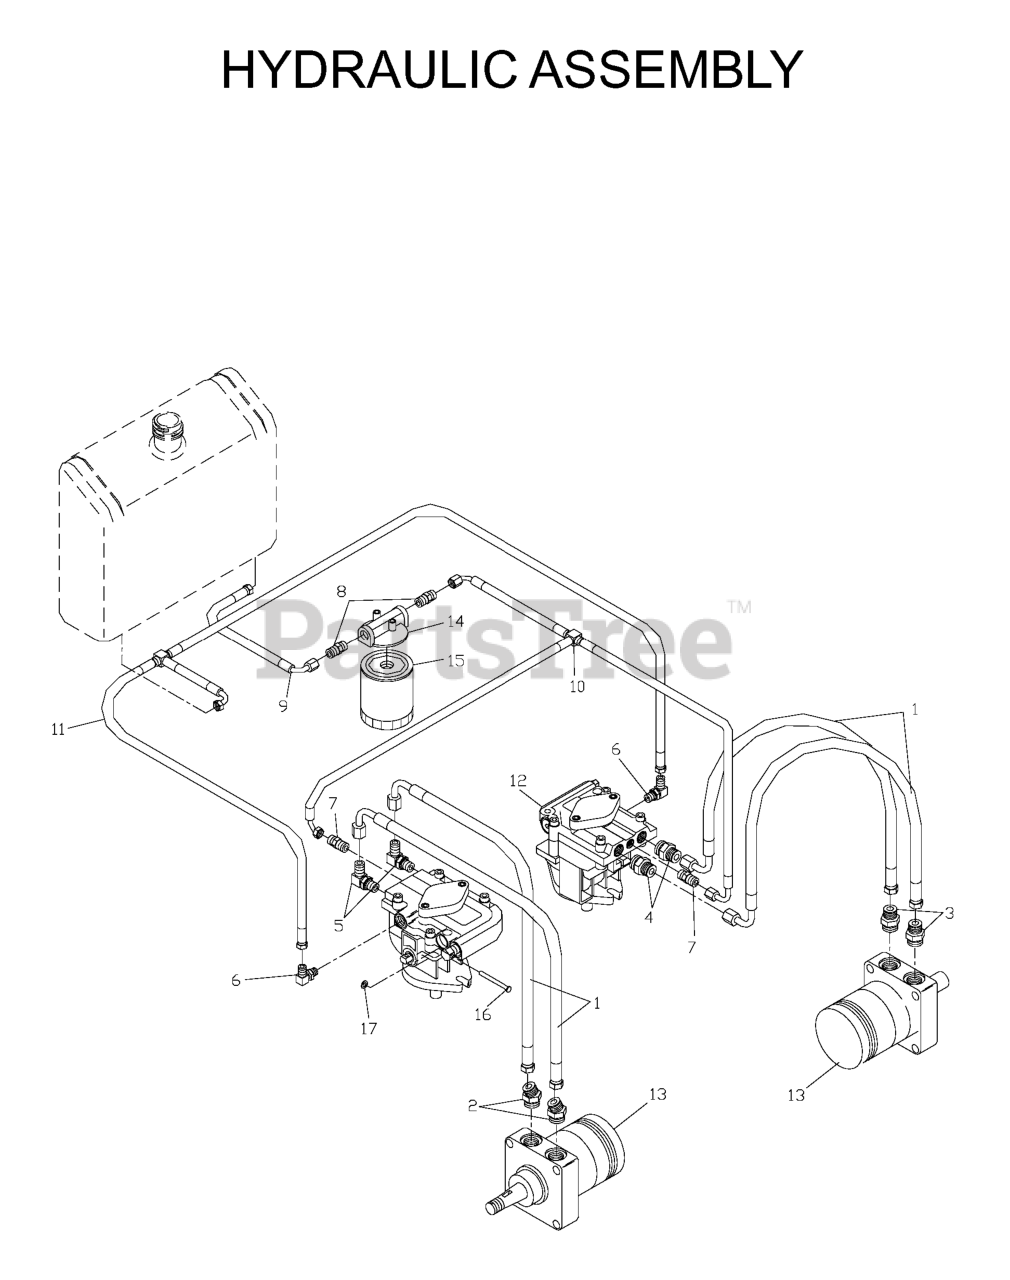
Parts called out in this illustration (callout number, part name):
1	HOSE, 1/2" HYDRAULIC
2	ELBOW-ADJ 45 DEG F6802-8-10
3	CONNECTOR, STRAIGHT
4	FITTING, STRAIGHT F6400-8-8-0
5	ELBOW, 90 DEGREE
6	ELBOW, F6801-6-6-0 90 DEGREE
7	FITTING, STRAIGHT F6400-6-4-0
8	STRAIGHT FITG
9	HOSE
10	INLET TEE HOSE
11	RETURN TEE HOSE
13	WHEEL MOTOR
14	FILTER HEAD
15	HYDRAULIC OIL FILTER
16	CLEVIS PIN
17	NUT PUSH
